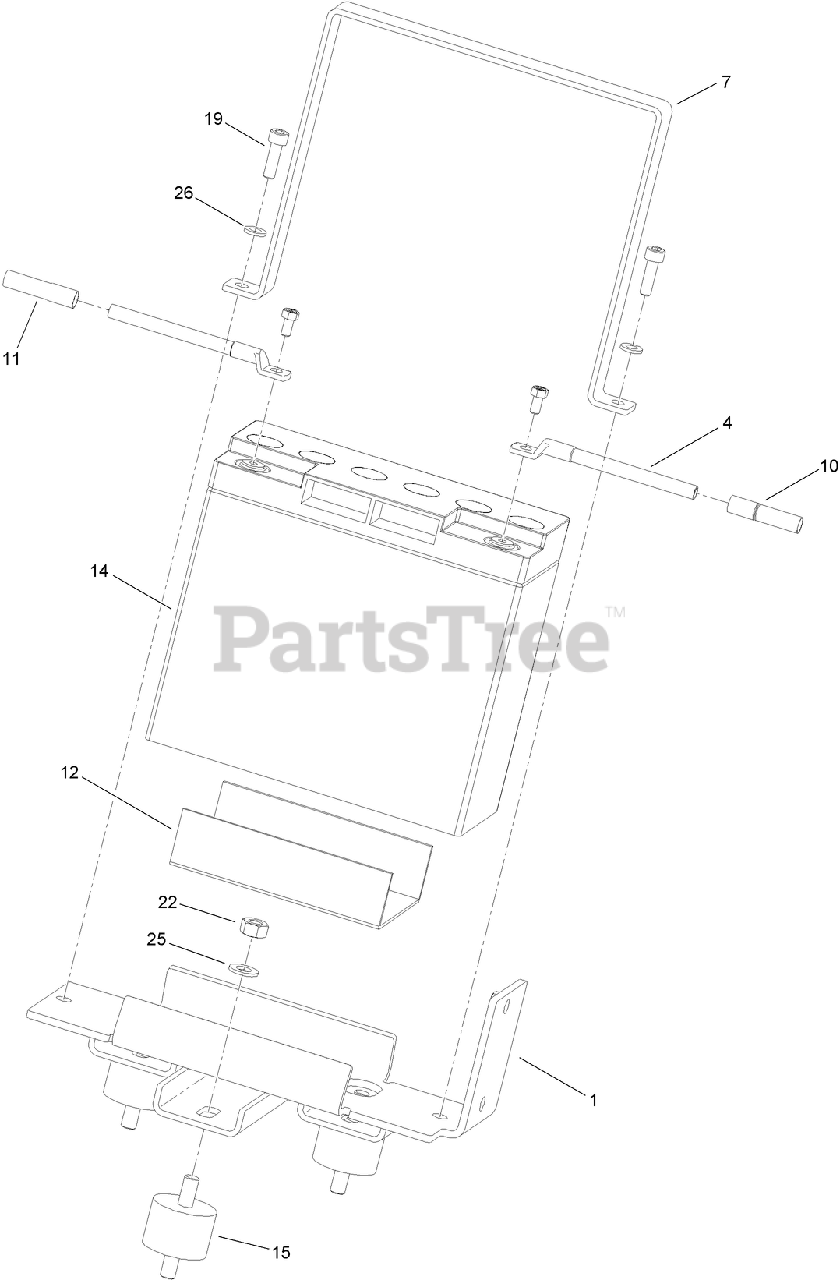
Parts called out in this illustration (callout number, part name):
1	CARRIER-BATTERY
4	WIRE-BATTERY
7	HOLDER-BATTERY
10	TUBING-BLUE
11	TUBING-RED
12	RUBBER
14	BATTERY
15	MOUNT-RUBBER
25	WASHER
26	WASHER
